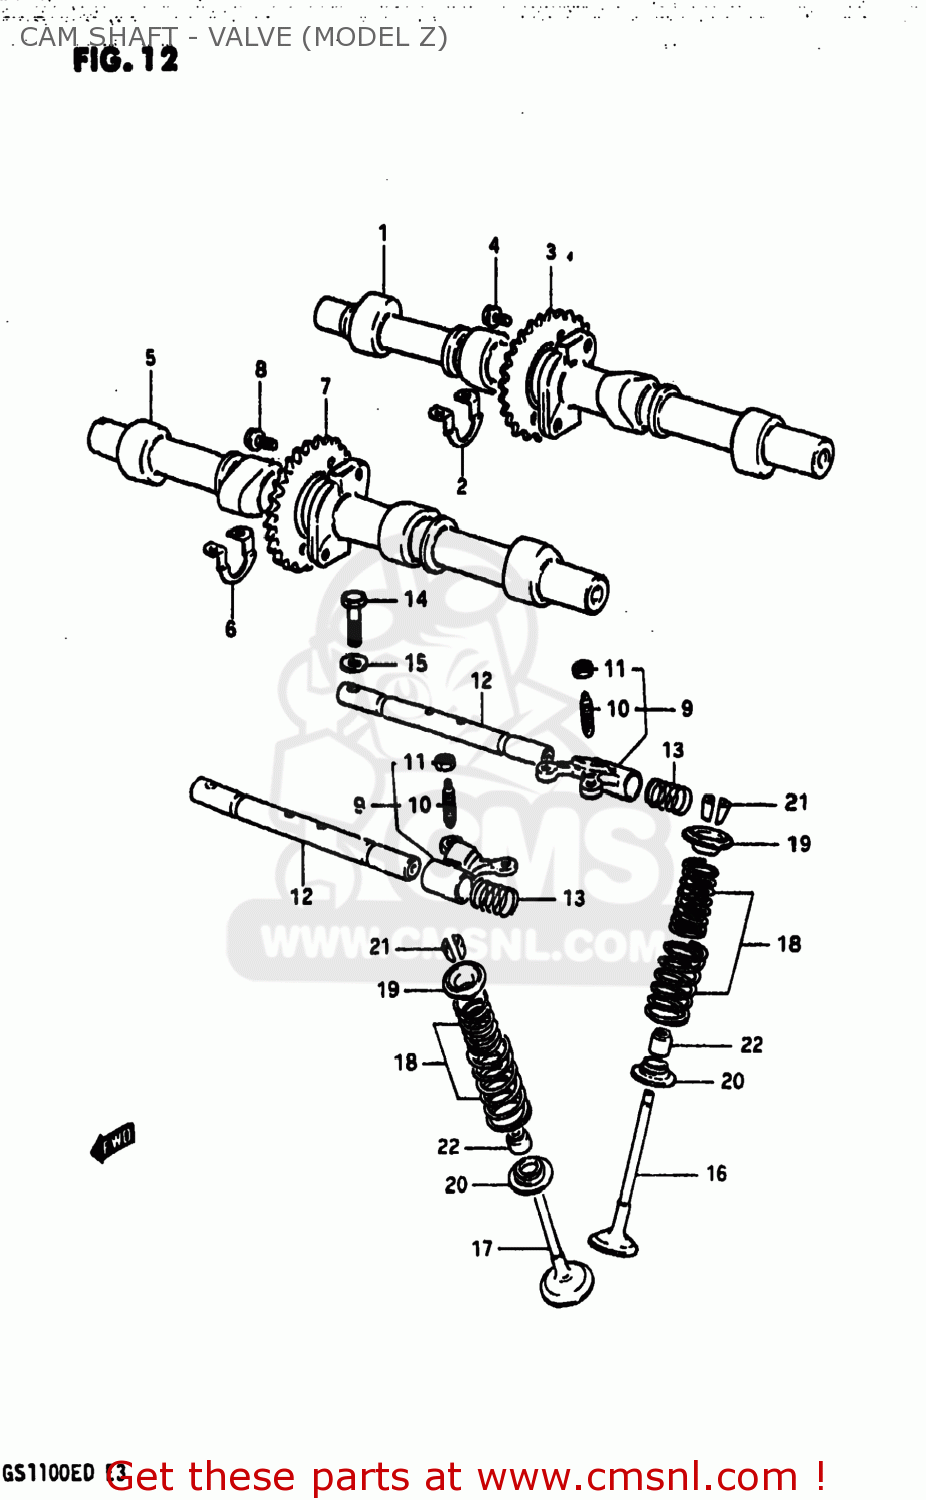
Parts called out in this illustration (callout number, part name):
1	CAMSHAFT,INTAKE
2	SHIM,CAMSHAFT
3	SPROCKET,INTAKE CAMSHAFT
4	BOLT(7X11)
5	CAMSHAFT SET,EXHAUST
6	SHIM,CAMSHAFT
7	SPROCKET,EXHAUST CAMSHAFT
8	BOLT(7X11)
9	ARM,VALVE ROCKER
10	SCREW,TAPPET ADJUSTING
11	NUT,ADJUSTING
12	SHAFT,VALVE ROCKER
13	SPRING
14	BOLT
15	WASHER
16	VALVE,INTAKE
17	VALVE,EXHAUST
18	SPRING SET,VALVE
19	RETAINER,VALVE SPRING
20	SEAT,VALVE SPRING
21	COTTER VALVE
22	OIL SEAL
